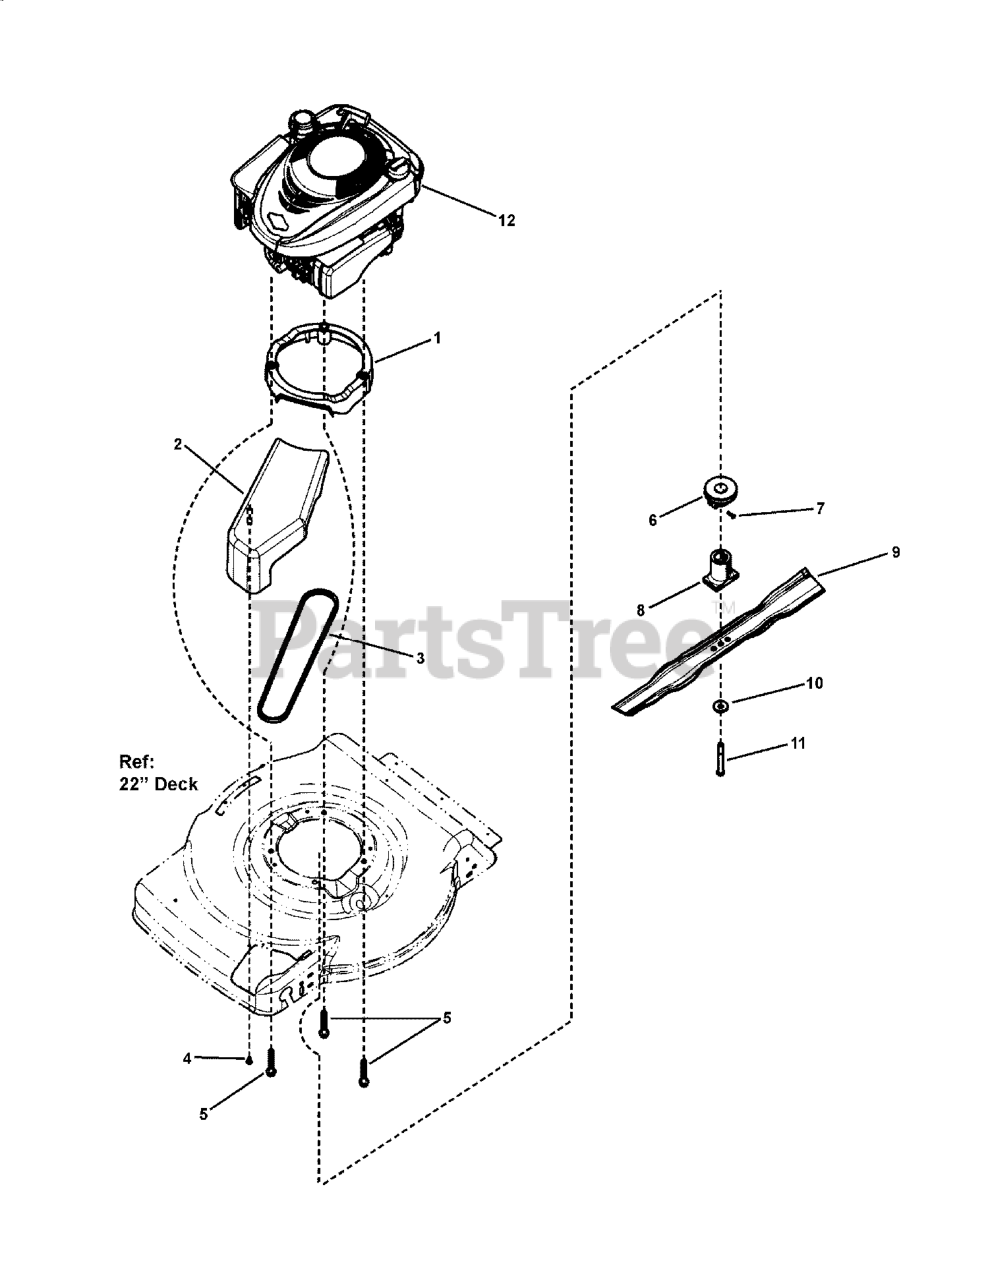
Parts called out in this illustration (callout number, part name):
1	ASSEMBLY, Engine Spacer, 22 WBM, Propelled
2	COVER, Belt, Plastic
3	BELT, Drive 22 WBM, SS
4	SCREW, 4.8MM X 1.59MM X 13MM, Torx Round Washer Head, HI-LO
5	BOLT, 3/8-16 x 2-1/2 Hex Washer Face
6	PULLEY, Engine, 22 Deck, Single Speed
7	SCREW, #8-11 x 5/8 Poly
8	HUB, Blade, 22 Deck
9	BLADE, 22 Walk Mower
10	WASHER, Bellville, .38 ID x 1.183 OD
11	BOLT, 3/8-24 x 3-1/4 Hex Head, GR 8
12	* ENGINE, 675 Series Quantum, Euro
